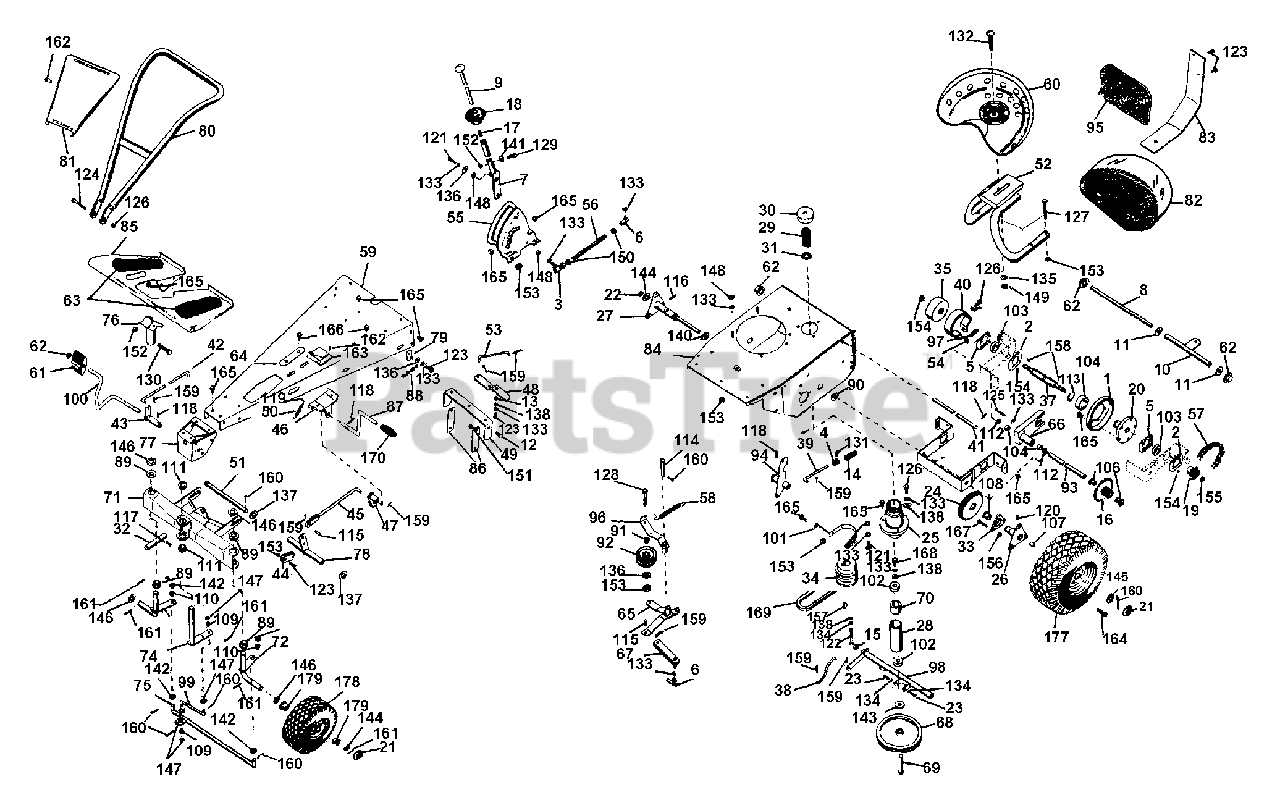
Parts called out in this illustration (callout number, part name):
1	FRICTION DISC
2	BEARING FLANGE
3	SNAP IN BALL JOINT
4	SET COLLAR
5	BEARING FLANGE
6	BALL JOINT
7	SHIFT LEVER
8	HITCH SHAFT
9	SHIFT RELEASE HANDLE
11	WAVE WASHER .531X.781X.125FH
12	SHOULDER BOLT .50 X .281
13	SPACER BUSHING .5 X .32 X .21
14	BRAKE SPRING
15	FORK SPACER
16	PINION & SPROCKET
17	SPRING
18	SHIFT BALL
19	9 TOOTH SPROCKET
20	FRICTION DISC HUB
21	HUB CAP
22	PUSHNUT
23	SCREW PIN
24	Differential Assembly
25	DRIVE SPRING HOUSING
26	L H AXLE
27	R H AXLE
28	DRIVE SPINDLE HOUSING
29	SPRING
31	SPRING RETAINER
32	AXLE PIVOT PIN
33	SUPPORT, BEARING
34	ENGINE SHEAVE
35	BRAKE DRUM
36	CARRIER
37	HEX SHAFT
39	BRAKE ROD
40	BRAKE BAND
41	DISC FORK ROD
42	FRONT CLTCH ROD
44	FRONT LINK
45	MOWER CLTCH LINK
46	MOWER CLUTCH BRACKET
47	MOWER OVERCENTER LEVER
48	CLTCH TRANSFER LEVER
49	HANGER BRACKET
50	SPRING
51	HANGER PIN
52	SEAT BRACKET
53	REAR CLTCH ROD
54	BRAKE BAND WASHER
55	SHIFT CNTL
56	SHIFT LINKS
57	CHAIN
58	IDLER SPRING
59	FRAME CHANNEL
60	SEAT
62	CAP, .50 ROD YWZC
63	FOOT PAD
64	GUIDE PLATE
65	SHIFT TRANSFER LEVER
66	SLIDING FORK
67	SHIFT LINK
68	DRIVE DISK
69	DRIVE SPINDLE
70	BEARING SPACER .87 X .63 X 1.2
71	FRONT AXLE ASSM
72	L H WHEEL SPINDLE
73	R H WHEEL SPINDLE
74	CENTER STEER COL
75	TIE ROD
76	STEER BLOCK
77	FRONT FRAME ASSM
78	MOWER CLUTCH LEVER
79	BLADE BRAKE
80	HANDLE BAR
81	HANDLE BAR PANEL
82	SEAT COVER
83	SEAT BACK SUPPORT
84	REAR FRAME
85	FOOT REST
86	HANGER LINK
87	MOWER CLTCH PEDAL
88	BRAKE RELEASE CHAIN
89	FLANGE BUSHING
90	FLANGE BUSHING
91	SPCR, BRG .315X.50X.688X.281
92	IDLER
93	CARR SHFT
94	BRAKE BELLCRNK
95	BACK REST
96	IDLER ARM
97	SPRING
99	STEERING LINK
101	REAR BELT FINGER
102	BRG-BALL .625X1.375X.44
103	BRG-BALL .500X1.38X.437
104	BRG-BALL 1.25X2.18X.63
105	BSHG-SLV .625X.750X.500
106	BSHG-FLG .625X.750X.500X.875BR
107	BSHG-SLV .562X.625X.625 BRZ
108	BSHG-FLG.875X1X.625X1.250 BR
109	BSHG-FLG .372X.500X.312X.625NY
110	BSHG-FLG.500X.625X.312X.750NY
111	BSHG-FLG.750X1X.375X1.250 IC
112	SEAL .625X.875X.125
113	RG-RTNG-EXT 1.250X.050
114	PIN-CLEVIS .500 X 3.250
115	CLEVIS PIN
116	PIN-ROLL .188X1.25
117	PIN-ROLL .250X1.25
118	PIN-ROLL .250X1.25
119	PIN-GRV .188X.75 TP G
120	HYDRAULIC DRIVE FITTING
121	BLT-HEX .31-18X1.00 PL GR 2
122	BLT-HEX .25-20X.75 PL GR2
123	BLT-HEX .31-18X.63 PL GR 2
124	BLT-HEX .31-18X1.00 PL GR 2
125	BLT-HEX .31-18X1.00 PL GR 2
126	BLT-HEX .31-18X1.00 PL GR 2
127	BLT-HEX .38-16X1.00 PL
128	BLT-HEX .38-16X1.50 PL GR2
129	BLT-HEX .44-14X1.25 PL GR2
130	BLT-HEX .44-14X1.25 PL GR2
131	SCR-SET .25-20X.50 SQHCUP HT
132	BLT-RDHDSQNK .50-13X1.25 PL
133	WSHR-LK .312X.097 PL HVY
134	WSHR-LK .375X.115 HVY PL
135	WSHR-LK .500X.151 HVY PL
136	WSHR-FL-STL .38X.875X.083 PL
137	WSHR-FL-STL .531X1.062X.095 PL
138	BRG-CUP1.980X.420
139	WSHR-FL-STL .38X.875X.083 PL
140	WSHR-FL-STL .531X1.062X.095 PL
141	WSHR-FL-STL .531X1.062X.095 PL
142	BRG-NEEDLE .625X.812X.50
143	BRG-BALL .625X1.375X.44
144	WSHR-FL-STL .755X2.000X.125
145	BRG-CONE .750X.61
146	BRG-CUP 3.346X.532
147	WSHR-FL-STL .812X2.000X.148
148	NUT-JAM .375-16 PL
149	NUT-JAM .625-11
150	NUT-HEX .312-24 PL
151	NUT-LK-CTR .375-16 GR A PL
152	NUT-LK-CTR .250-20 PL
153	NUT-LK .312-18 GR A PL
154	NUT-KEPS 10-24 PL
155	NUT-LK-CTR .50-20 PL
156	NUT-LK-FLG .250-20 PL
157	KEY-WDRF .156X.625X.25 SAE 6
158	KEY-WDRF .188X.875X.375 SAE11
159	PIN-COTR .09X.75 PL
160	PIN-COTR .12X1.0 PL
161	PIN-COTR .09X.75 PL
162	RVT-POP.125 X .294 DOME
163	THROTTLE CONTROL
164	BRG-CUP 2.441X.562
165	BLT-SERHFWH .31-18X.50 PL
166	BLT-SCRHFWH .38-16X.50 PL
167	SCR-SLTR-SERNK .25-20X.62 PL
168	SCR-SL-FLSTR .38-16X.44 PL
169	V-BELT, SAE 380-RAW EDGE
176	MOWER IN-OUT LABEL
177	Tire and Wheel Assembly consisting of:
177	TUBE
177	WHL 6 IN O.D.
177	TIRE 12.5/4.50-6
178	Front Wheel Assembly consisting of:
178	BSHG-FLG.750X1X.375X1.250 IC
178	ZERK FITTING
178	TIRE 4.1/3.50X4
178	TUBE 4.1X3.5-4
178	WHL
179	BSHG-FLG .750X1.129X.750
